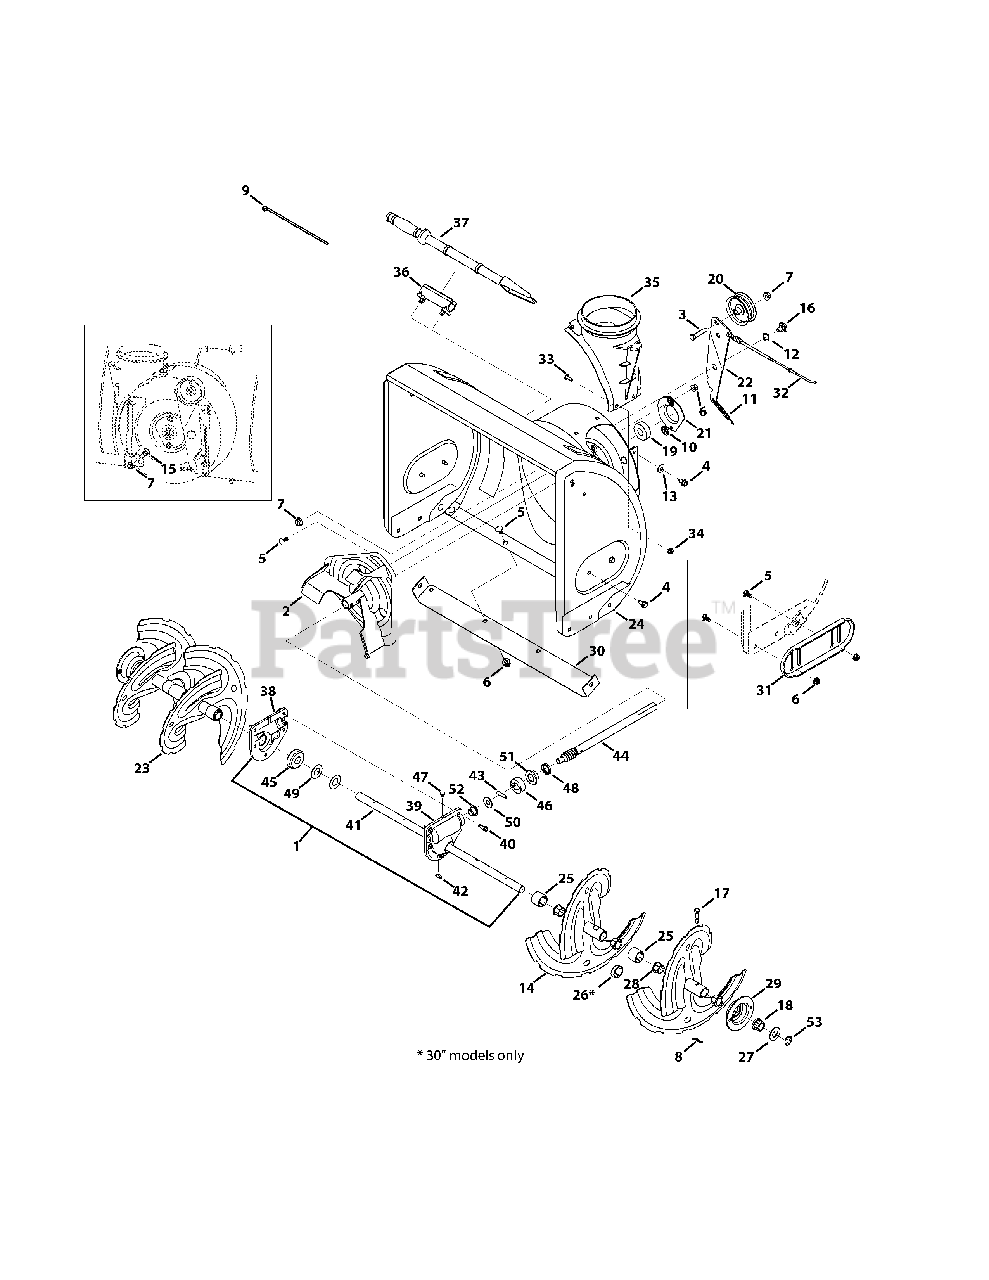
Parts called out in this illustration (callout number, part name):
1	Auger Gearbox 30"
2	Impeller Assembly, 12" Dia.
3	Hex Head Screw, 3/8-16 x 1.75
4	Screw, 5/16-18 x .750
5	Bolt, Carriage, 5/16-18 x .750
6	Nut, Flange lock, 5/16-18
7	Nut, Flange lock, 3/8-16
8	Bow-Tie Cotter Pin
9	Cable Tie, 7"
10	Nut, Push-on, .25 Dia.
11	Extension Spring, .38 x 4.59
12	Washer, Wave, .625 x .885
13	Washer, Bell, .340 x .872
14	Spiral Assembly, LH
15	Bolt, Shoulder, .496 x .336 x 3/8-16
16	Screw, Shoulder, .625 x .17 x 3/8-16
17	Shear Pin, .25 x 1.50
18	Hex Flange Bearing
19	Bearing, Ball, .75 x 1.85
20	Pulley, Idler, Flat, 2.75
21	Bearing, 1.85 ID
22	Auger Idler Bracket
23	Spiral Assembly, RH
24	Auger Housing Assembly, 30"
25	Spacer, 1.25 x .75 x 1.00
26	Spacer, 1.250 x .75 ID x 3/16 LG
27	Washer, Flat, .76 x 1.49
28	Bushing, Flange, .800 x .910
29	Hex Bearing Housing
30	Shave Plate, 2.25 x 29.66
31	Deluxe Slide Shoe
32	Auger Drive Clutch Cable
33	Screw, Carriage, 1/4-20 x .75
34	Nut, Flange lock, 1/4-20
35	Chute Adapter
36	Clean-Out Tool Mount
37	Clean-Out Tool
38	Reducer, RH
39	Reducer, LH
40	Screw, 1/4-20 x 0.750
41	Auger Axle, 30"
42	Key, Hi-Pro, 3/16 x 5/8
43	Dowel Pin, .25 x 1.25
44	Worm Shaft, .75
45	Gear Worm, 20T
46	Collar Thrust, .756 x .600
47	Plug, 1/4 x .437
48	Oil Seal, .75 x 1.131 x .188
49	Washer, Flat, .760 x 1.50
50	Washer, Flat, .51 x 1.12
51	Bearing, Flange, .75 x 1.00 x .59
52	Bearing, Flange, .50 x .75 x .59
53	E-Ring, .750
